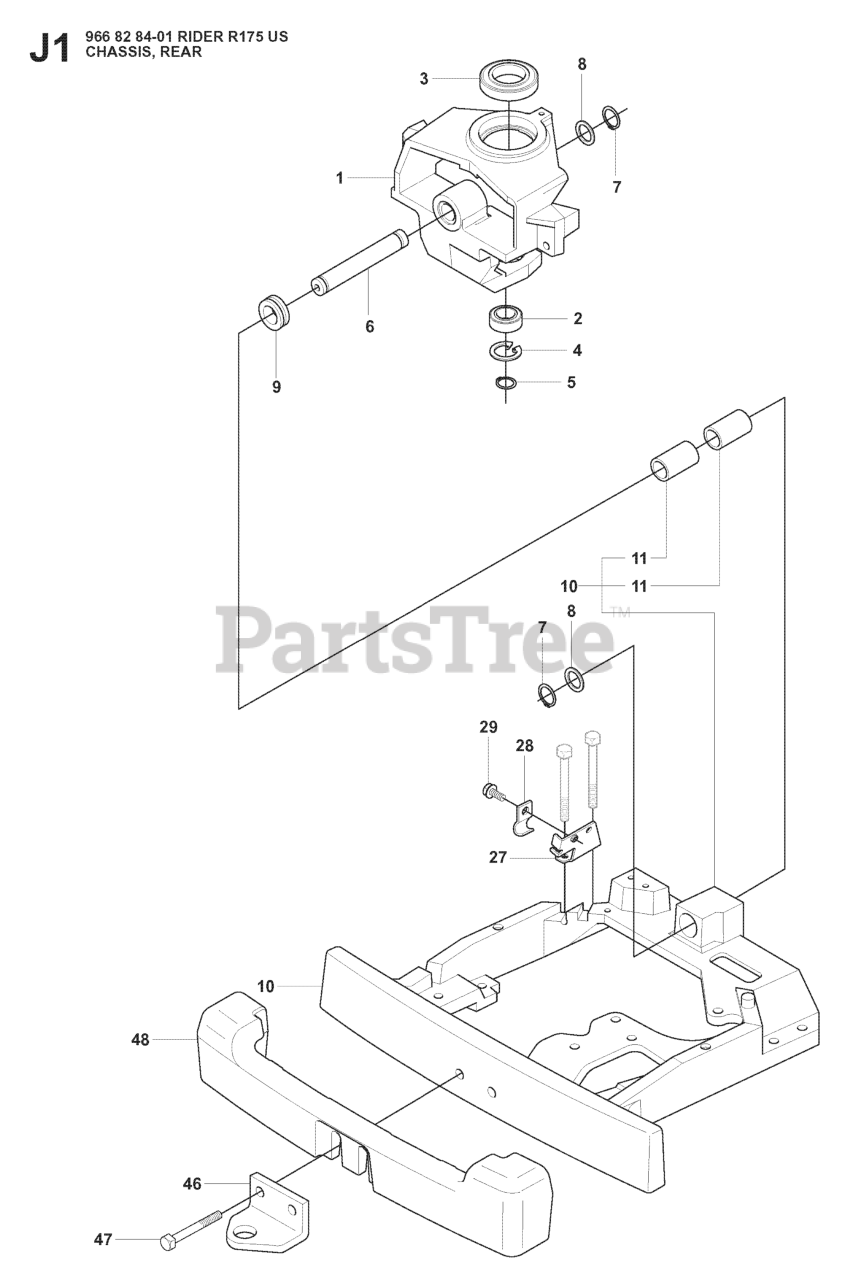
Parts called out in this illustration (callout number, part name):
2	Ball Bearing 6005-2rs
3	BALL BEARING 6010 2RS1
4	CIRCLIP SGH 47
5	RETAINING RING SGA 25
7	RETAINING RING SGA 25
47	REPL BY 725 25 00-71
48	COUNTERWEIGHT
